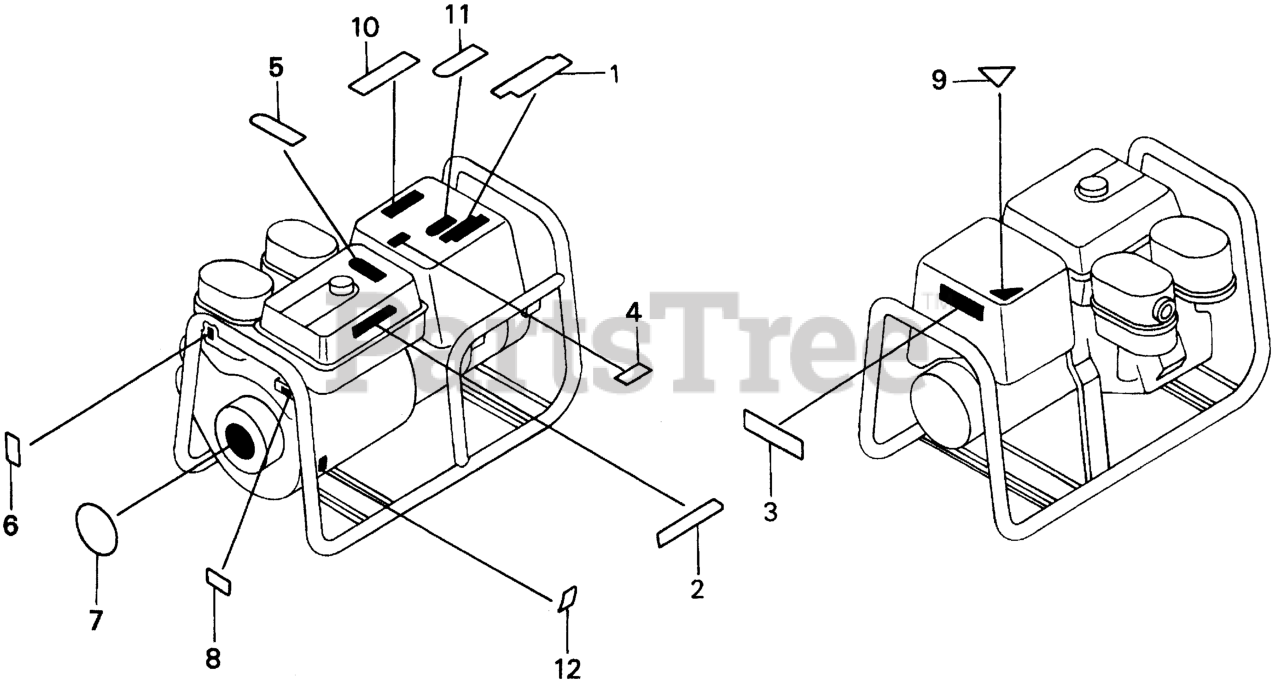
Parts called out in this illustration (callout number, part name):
1	MARK, EMBLEM (EG)
2	EMBLEM, FUEL TANK
3	PLATE, CAUTION
4	LABEL, RAIN WARNING (ENGLISH)
5	MARK, CAUTION (ENGLISH/FRENCH)(SPANISH)
6	MARK, CHOKE (EXTERNAL)
7	MARK, OIL ALERT (NOT AVAILABLE)
8	MARK, OIL ALERT (EXTERNAL)
10	MARK, CAUTION (CO)(ENGLISH/FRENCH)(SPANISH)
11	LABEL, CONNECT WARNING (ENGLISH)
12	MARK, OIL CAUTION
